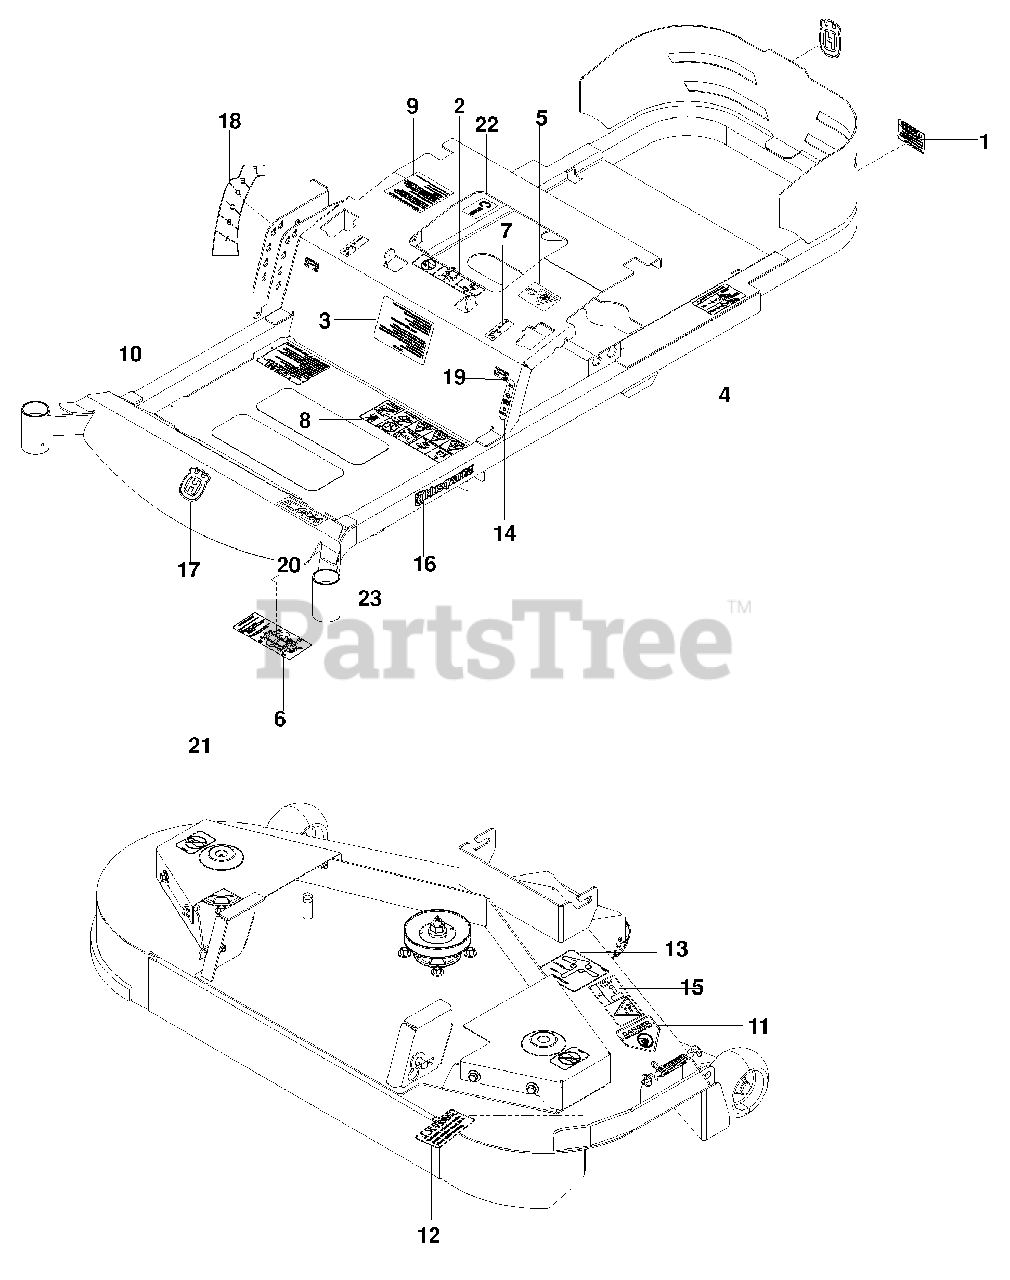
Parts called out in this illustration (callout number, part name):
1	Decal, Prop 65
2	Decal, Battery Warning
3	Decal, Start
4	Decal, Do Not Tow
5	Decal, Exit Mower
6	Decal, Service
7	Decal, Motion Control
8	Decal, Safety Graphics
9	Decal, Responsibility
10	Decal, Safety Warn
11	Decal, Blade Warning
12	Decal, Discharge Warn
13	Decal, Belt Routing
14	Decal, Park Brake
15	Decal, Severing
16	Decal, Husqvarna
17	Decal, Crown H
18	Decal, Height
19	Decal, Fst
20	Decal, Ez4824
21	Decal, No Step
22	Decal, Ecm
23	Abrasive Pad
